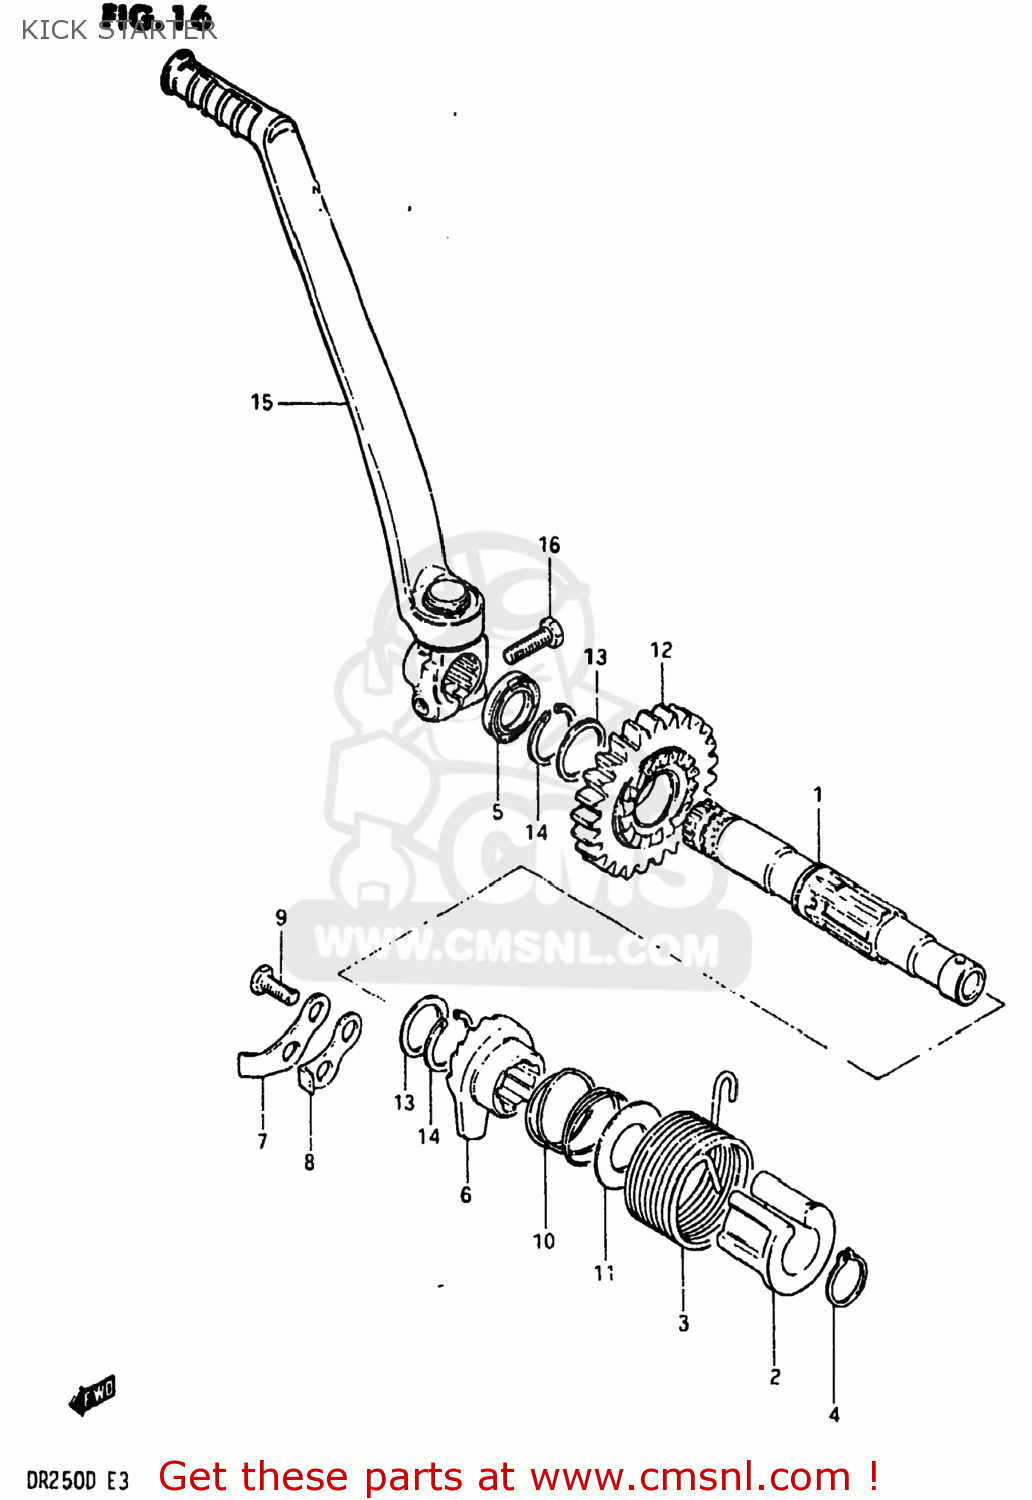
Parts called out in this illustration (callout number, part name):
1	SHAFT,KICK STARTER
2	GUIDE,KICK STARTER SFT SPRING
3	SPRING
4	CIRCLIP
5	SEAL,OIL(20X27X5)
6	STARTER,KICK
7	GUIDE,KICK STARTER
8	STOPPER,KICK STARTER
9	BOLT
10	SPRING
11	WASHER
12	GEAR,KICK STARTER DRIIVE
13	SHIM
14	CIRCLIP
15	LEVER ASSEMBLY,KICK STARTER
16	BOLT 8X25
